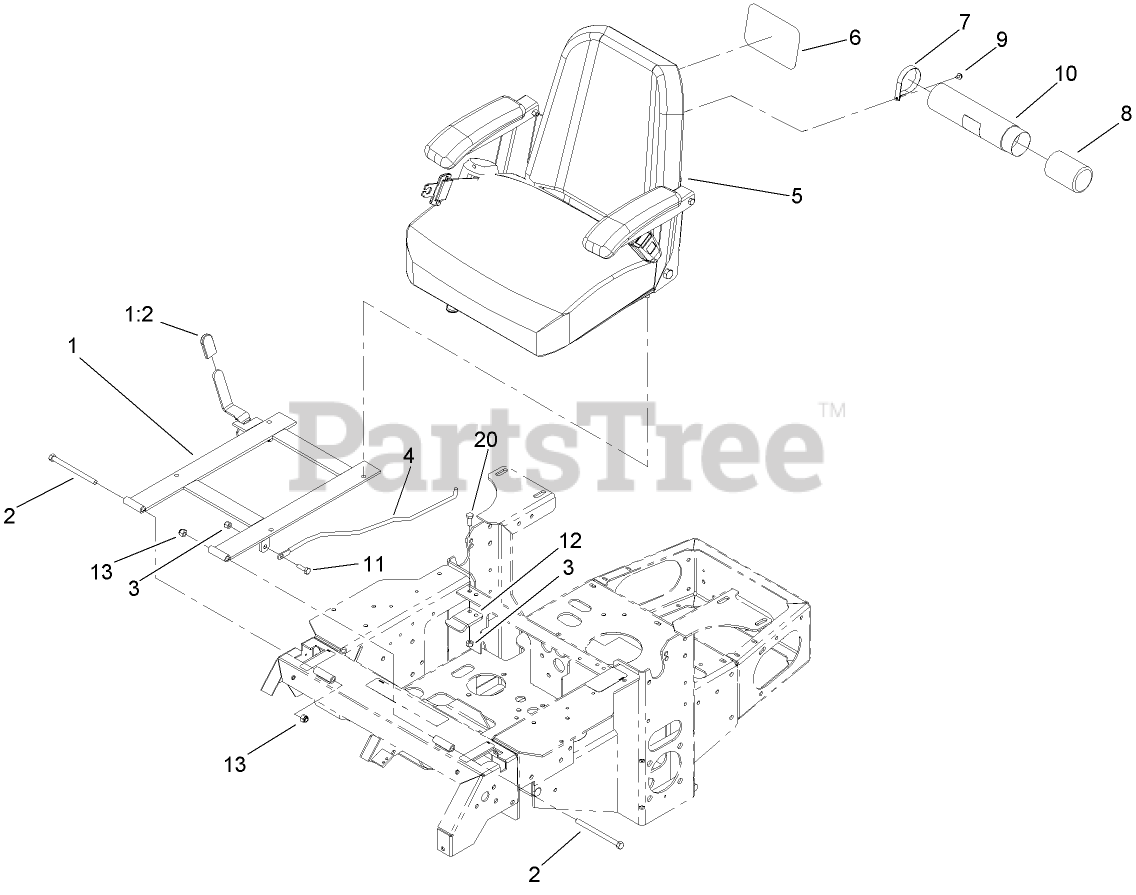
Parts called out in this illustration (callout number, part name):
1	SEAT FRAME AND LATCH ASM
1:2	GRIP-LEVER
2	SCREW-HH
3	NUT-LOCK, NI
4	ROD-RETAINER, SEAT
5	SEAT ASM
6	DECAL
7	CLAMP-R
8	CAP-HOUSING
9	SCREW-HWHTF
10	TUBE-MANUAL
11	SCREW-HH
12	CATCH-LATCH, SEAT
13	NUT-LOCK, NI
20	SCREW-HH
